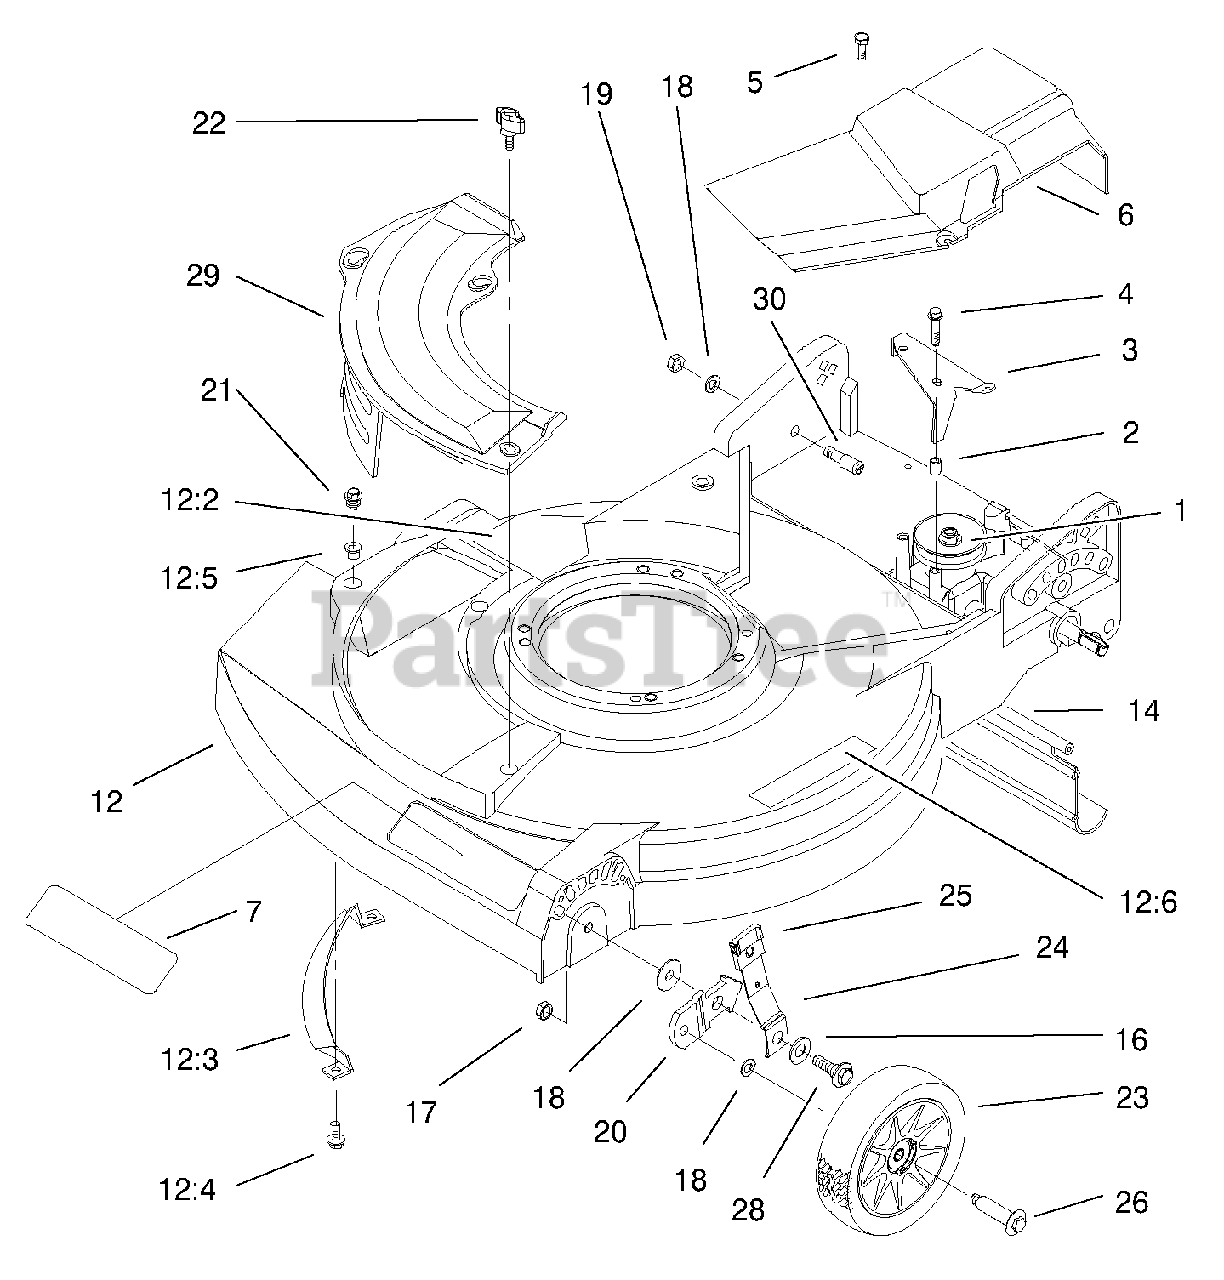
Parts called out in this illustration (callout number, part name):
1	Gear Case ASM
3	Bracket-Actuator
4	Screw-HWH
6	Cover-Drive
7	Decal-Deck
12	Housing ASM
12:2	Decal-Danger
12:3	Toe Bar
12:4	Screw-HWH
12:5	Grommet-Plastic
12:6	Decal-Warning
14	Shield-Trailing
16	Washer-Belleville
17	Nut-Lock, NI
20	Bracket-Wheel Height Adjustment
21	Screw-Sems
23	Wheel & Tire ASM
24	Spring Arm ASM-Front
25	Knob-Lever, Height Adjustment
26	Bolt-Shoulder
28	Bolt-Shoulder
29	Plate-Mulch
30	Screw-Torx
